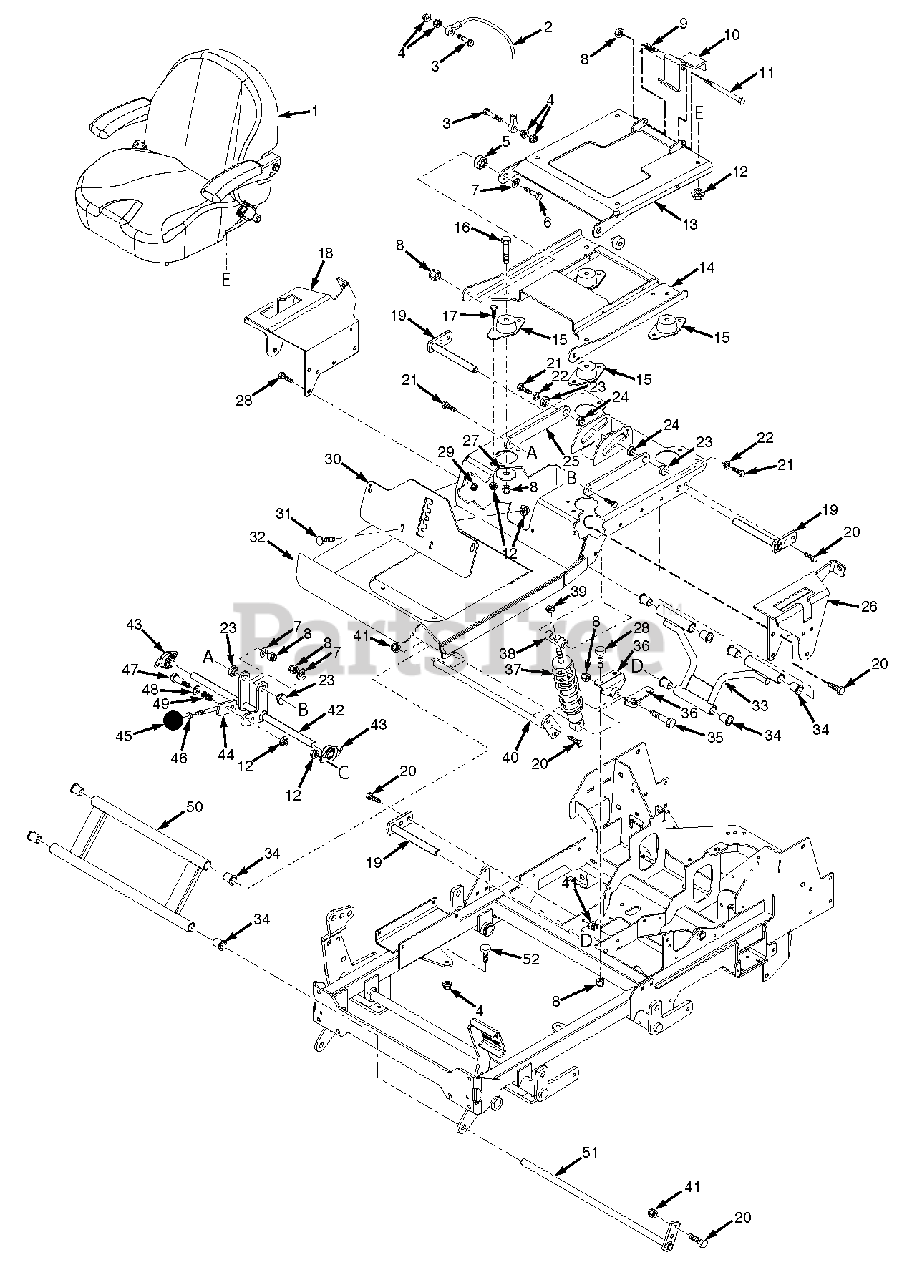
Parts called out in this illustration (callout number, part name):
1	Seat Assembly
2	Cable, Seat Stop
3	Bolt, Hex Head 1/4-20 x 1-1/4"
4	Nut, Serrated Flange 1/4-20
5	Sleeve, Seat Base Mount
6	Bolt, Hex Head 3/8-16 x 2"
7	Flatwasher, 3/8-.391 x .938 x .105
8	Nut, Elastic Stop 3/8-16
9	Spring, Seat Latch
10	Latch Weldment, Seat
11	Bolt, Hex Head 3/8-16 x 6"
12	Nut, Serrated Flange 5/16-18
13	Seat Plate Weldment
14	Seat Mounting Plate Weldment w/Decal
15	Isolator, Seat
16	Bolt, Hex Head 3/8-16 x 2-1/4"
17	Bolt, Hex Head 5/16-18 x 3/4"
18	Bracket Weld., Control Lever RH w/Decal
19	Shaft Weldment, Rear Op. Platform Pivot
20	Bolt, Hex Head 5/16-18 x 1"
21	Bolt, Hex Head 3/8-16 x 1-1/2"
22	Lockwasher, 3/8" Spring
23	Bushing
24	Bearing
25	Link, Suspension Seat Tensioner
26	Bracket Weld., Control Lever LH w/Decal
27	Flatwasher, 3/8-.406 x 2.25 x .188
28	Bolt, Hex Head 3/8-16 x 1"
29	Nut, Serrated Flange 3/816
30	Bracket, Suspension Adjustment w/Decal
31	Bolt, Carriage 5/16-18 x 1"
32	Seat Mounting Base Weldment w/Decal
33	Suspension Pivot Assembly, Rear
34	Bearing
35	Bolt, Hex Head 3/8-16 x 2-3/4"
36	Mount Weldment, Shock
37	Shock Absorber, Suspension
38	Mount, Suspension Shock
39	Nut, Elastic Stop 3/8-24
40	Pin Weldment, Op Platform Upper Pivot
41	Nut, Elastic Stop 5/16-18
42	Pivot Weldment, Suspension Tensioner
43	Bearing, Self Align 5/8" ID
44	Adjustment Lever, Suspension
46	Nut, Jam 3/8-16
47	Bolt, Shoulder 3/8 x 1"
47	Bolt, Shoulder 3/8 x 3/8"
48	Flatwasher, 3/8-.406 x .812 x .065
49	Spring
50	Suspension Pivot Assembly, Front
51	Pin Weldment, Op Platform Lower Pivot
52	Bumper, Rubber
